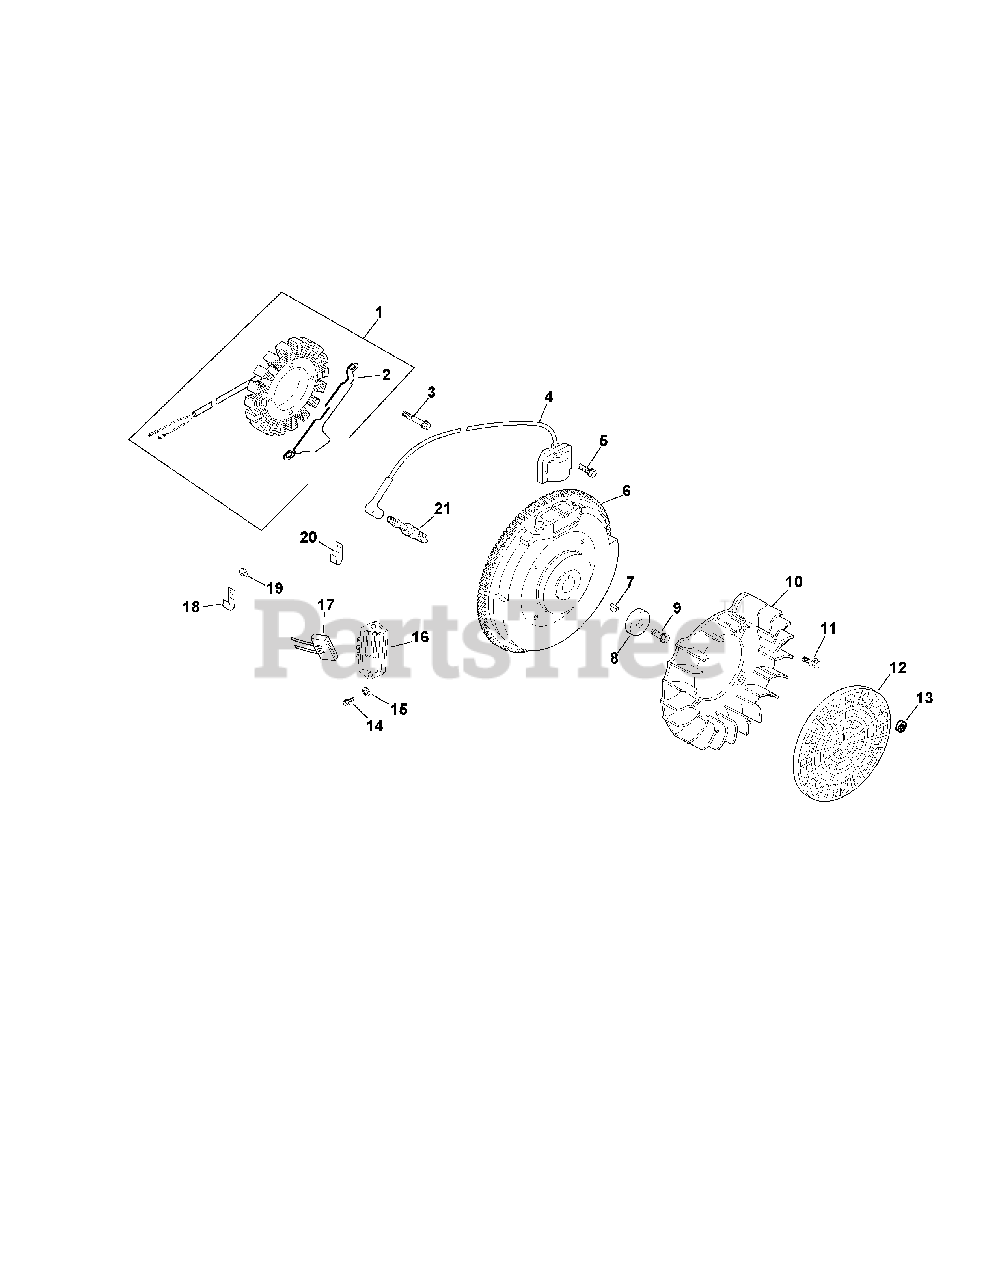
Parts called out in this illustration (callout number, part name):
1	Kit, 15 amp stator (Includes 2)
2	Bracket, stator wire
3	Screw, hex cap M5x0.8x25 (2)
4	Module, ignition (2)
5	Screw, hex flange M5x0.8x20 (4)
6	Flywheel
8	Washer, plain 3/8"
9	Screw, hex flange M10x1.5x46
10	Fan
11	Bolt, shoulder (4)
12	Screen, grass
13	Retainer, grass screen (3)
14	Screw, phillips hd 11-16x7/8" (2)
15	Washer, plain 3/16" (2)
16	Rectifier-regulator 15 amp
17	Connector (3 contact)
18	Clip, cable
19	Washer, plain 1/4"
21	Spark Plug
